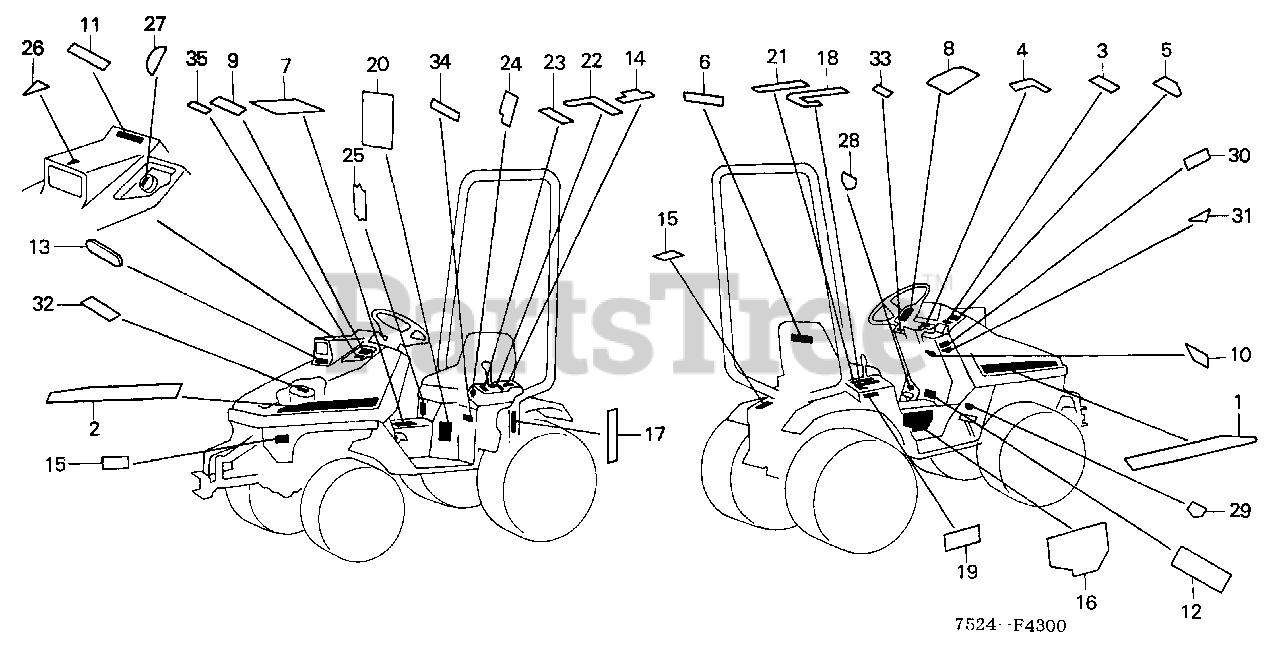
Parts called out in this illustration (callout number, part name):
1	MARK, R. SIDE STRIPE
2	MARK, L. SIDE STRIPE
3	MARK, LIGHT OPERATING (ENGLISH)
4	MARK, ENGINE SWITCH OPERATION (ENGLISH)
5	MARK, THROTTLE OPERATING (ENGLISH)
6	MARK, SEAT
7	LABEL A, WARNING (ENGLISH)
8	LABEL, CAUTION (ENGLISH)
9	LABEL, FUEL WARNING (B)(ENGLISH)
10	MARK, BRAKE LOCK INDICATION (ENGLISH)
11	LABEL, OPEN CAUTION (ENGLISH)
12	LABEL, PARKING BRAKE (ENGLISH)
13	EMBLEM, HEADLIGHT CASE
14	MARK, P.T.O. INDICATION (ENGLISH)
15	LABEL B, WARNING (ENGLISH)
16	LABEL, DIFFERENTIAL CAUTION (ENGLISH)
17	LABEL, ROLL OVER PROTECTIVE STRUCTURE WARNING (ENGLISH)
18	MARK, LIFT INDICATION (ENGLISH)
19	LABEL, HYDRAULIC ADJUST OPERATION (ENGLISH)
20	MARK, RECOMMENDED WORK SPEED (ENGLISH)
22	MARK A, MAIN CHANGE INDICATION (ENGLISH)
23	MARK B, MAIN CHANGE INDICATION (ENGLISH)
24	MARK, SUB-CHANGE INDICATION (ENGLISH)
25	MARK, CHANGE INDICATION (2/4WD)
26	MARK, CENTER POINT
27	MARK, FUEL INDICATION (ENGLISH)
28	MARK, CLUTCH INDICATION (ENGLISH)
29	MARK, BRAKE INDICATION (ENGLISH)
30	MARK A, FR. P.T.O. INDICATION (ENGLISH)
31	MARK B, FR. P.T.O. INDICATION (ENGLISH)
32	LABEL, AIR CLEANER CAUTION (ENGLISH)
33	MARK, CHOKE INDICATION (ENGLISH)
35	LABEL, FUEL CAUTION
